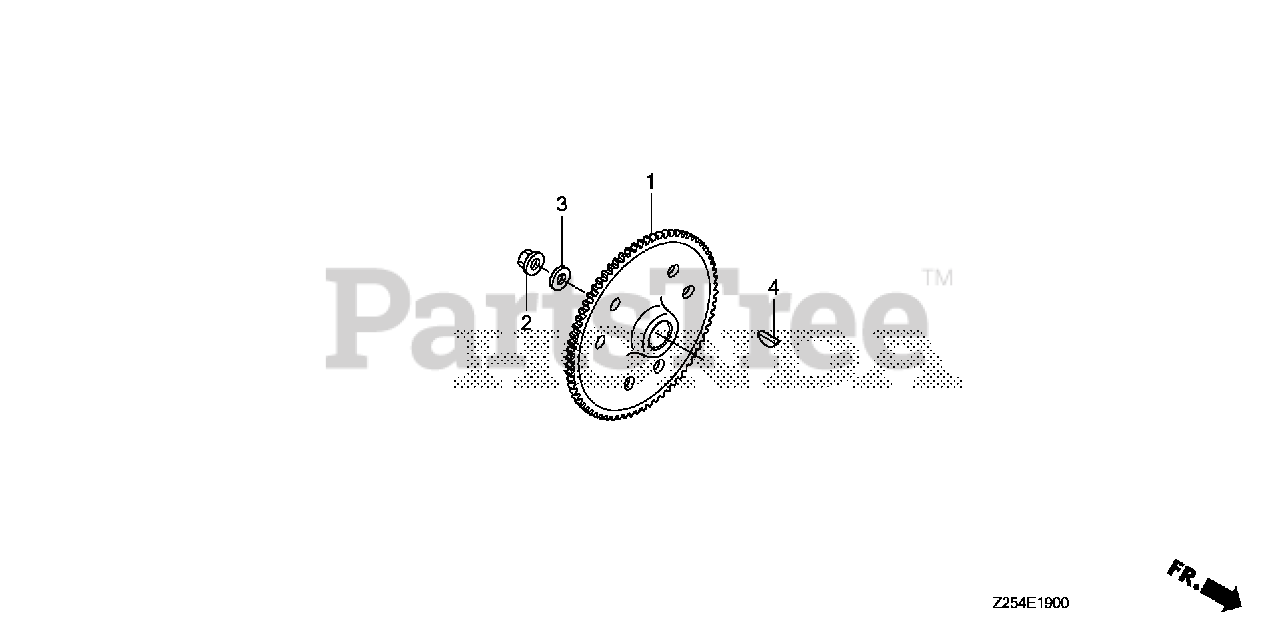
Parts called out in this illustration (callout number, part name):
2	NUT, SPECIAL (16MM)
3	WASHER, FLYWHEEL
4	KEY, SPECIAL WOODRUFF (25X18)
